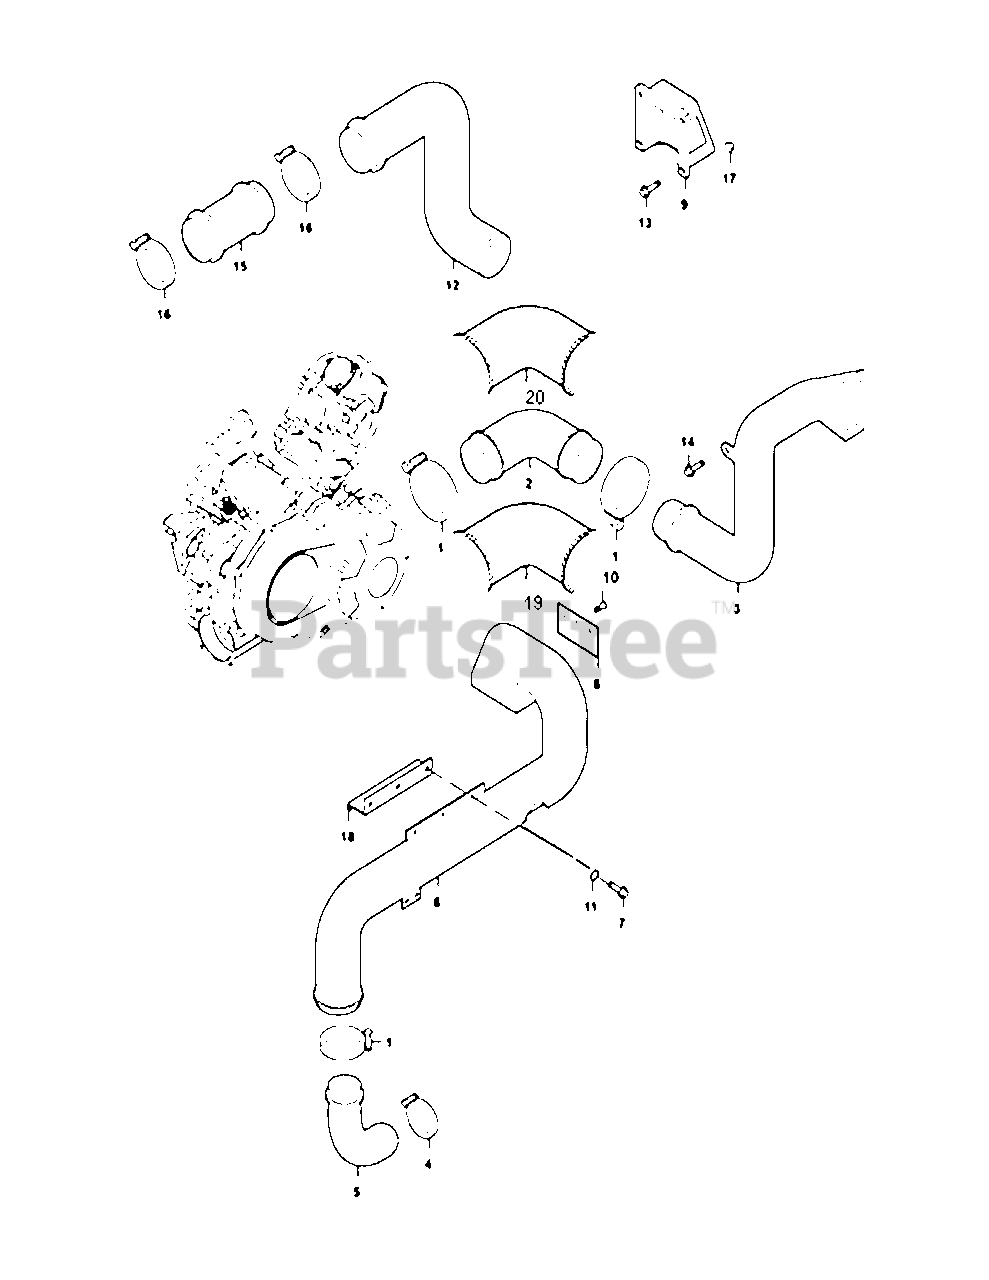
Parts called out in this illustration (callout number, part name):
1	Clamp 250
2	Inlet Pipe Joint, Clutch
3	Inlet Pipe, Clutch
4	Clamp 240
5	Inlet Pipe Joint, Clutch
6	Air-Out Pipe,Clutch
7	Hexagon Flange Bolt M6×16
8	Air-Out Pipe Dustproof Rubber, Clutch
9	Air-In Pipe Dustproof Cover, Clutch
10	Expansion Bolt(Plastic)
11	Washer6×18×1.6
12	Air-Out Pipe, Fan
13	Cross Large Plate Head Screw M6×12
14	Cross large plate head screw M6×16
15	Air-Out Joint, Fan
16	Clamp
17	Hexagon Flange Nut M6
18	Air-Out Pipe Mounting Board,Clutch
19	Inlet Pipe Joint insulation paper I
20	Inlet Pipe Joint insulation paper II
